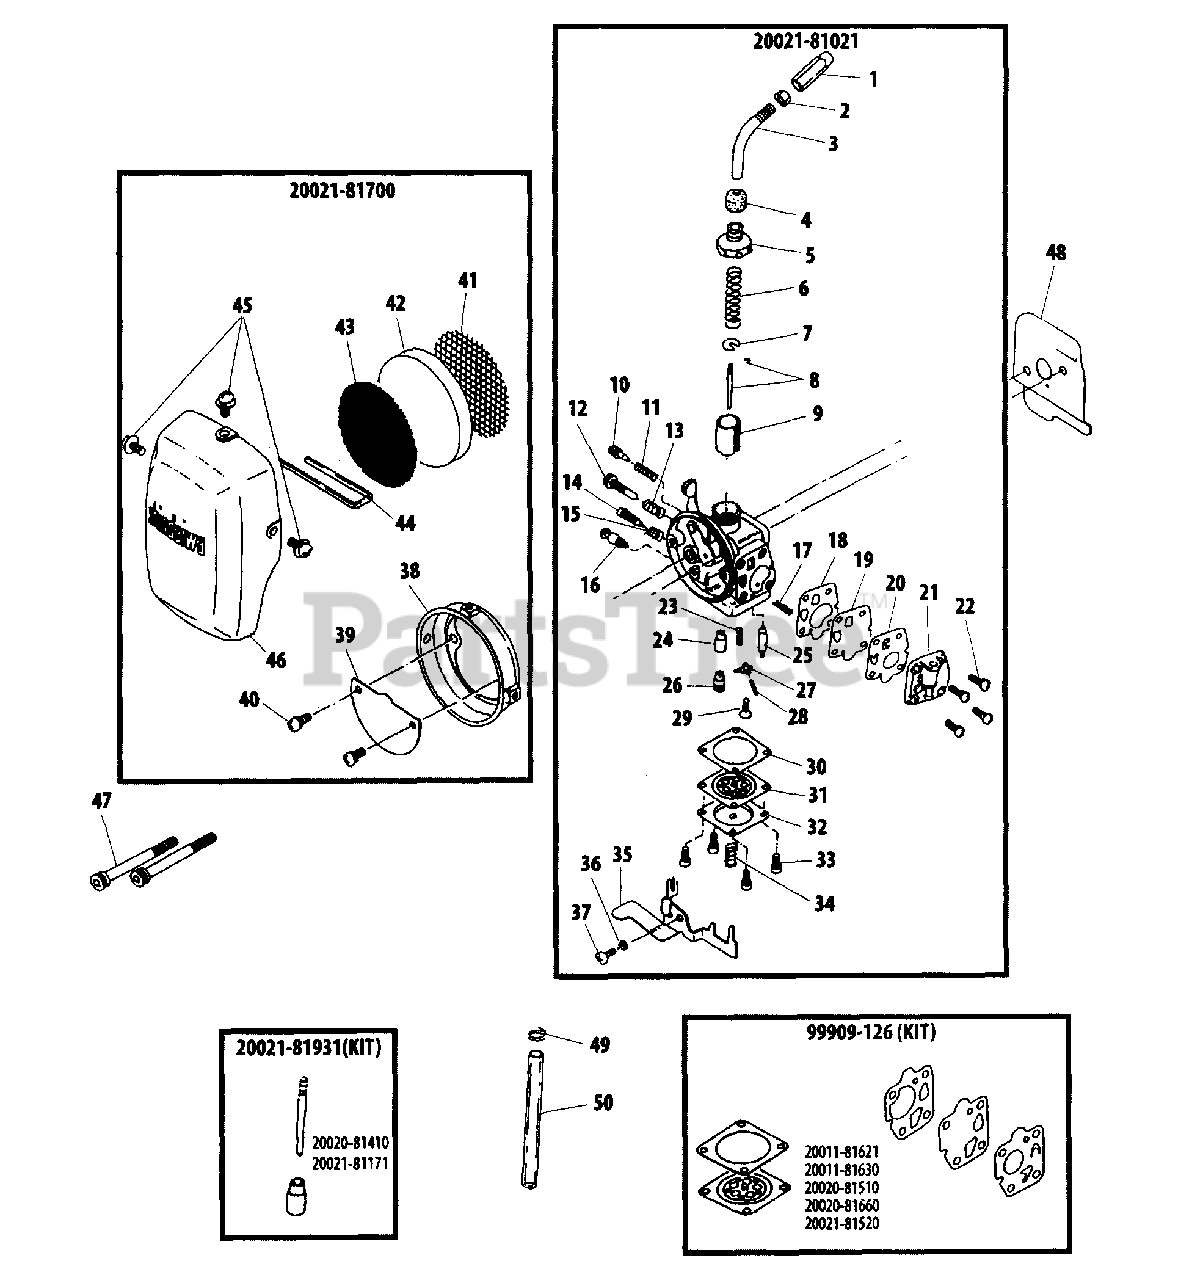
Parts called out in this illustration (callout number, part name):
1	ADJUSTER, CABLE
2	NUT, LOCK
3	PIPE, CABLE ADJUSTER(4 pieces ×2 M)
4	CAP
5	CAP, CARBURETOR
6	SPRING, THROTTLE
7	WASHER
8	NEEDLE, JET
9	VALVE, THROTTLE
10	SCREW, SLOW AIR
11	SPRING
12	SCREW, IDLE ADJUST
13	SPRING
14	SCREW, ADJUST
15	SPRING
16	VALVE, OVERFLOW
17	SPRING, COIL
18	GASKET, DIAPHRAGM
19	DIAPHRAGM, METERING
20	VALVE, PUMP
21	BODY, PURGE
22	SCREW
23	SPRING, VALVE
24	JET, MAIN
25	VALVE, INLET NEEDLE
26	HOLDER, MAIN JET
27	LEVER, METERING
28	PIN, METERING LEVER
29	SCREW, METERING LEVER PIN
30	GASKET
31	DIAPHRAGM, METERING
32	COVER, METERING DIAPHRAGM
33	SCREW M3×8
34	SPRING
35	LEVER, TICKLER
36	COLLAR
37	SCREW
38	CASE, AIR FILTER
39	PLATE
40	SCREW
41	SCREEN, REAR
42	FILTER, AIR
43	SCREEN - FRONT
44	CLIP, FILTER RETAINING
45	SCREW 4
46	COVER, AIR FILTER
47	BOLT M5×48
48	SHIELD, INTAKE
49	CLIP Ø6
50	PIPE, FUEL
20021-81021	CARBURETOR DPW12-1A
20021-81700	FILTER ASSY, AIR
20021-81931	NEEDLE / JET KIT
99909-126	DIAPHRAGM/GASKET KIT
